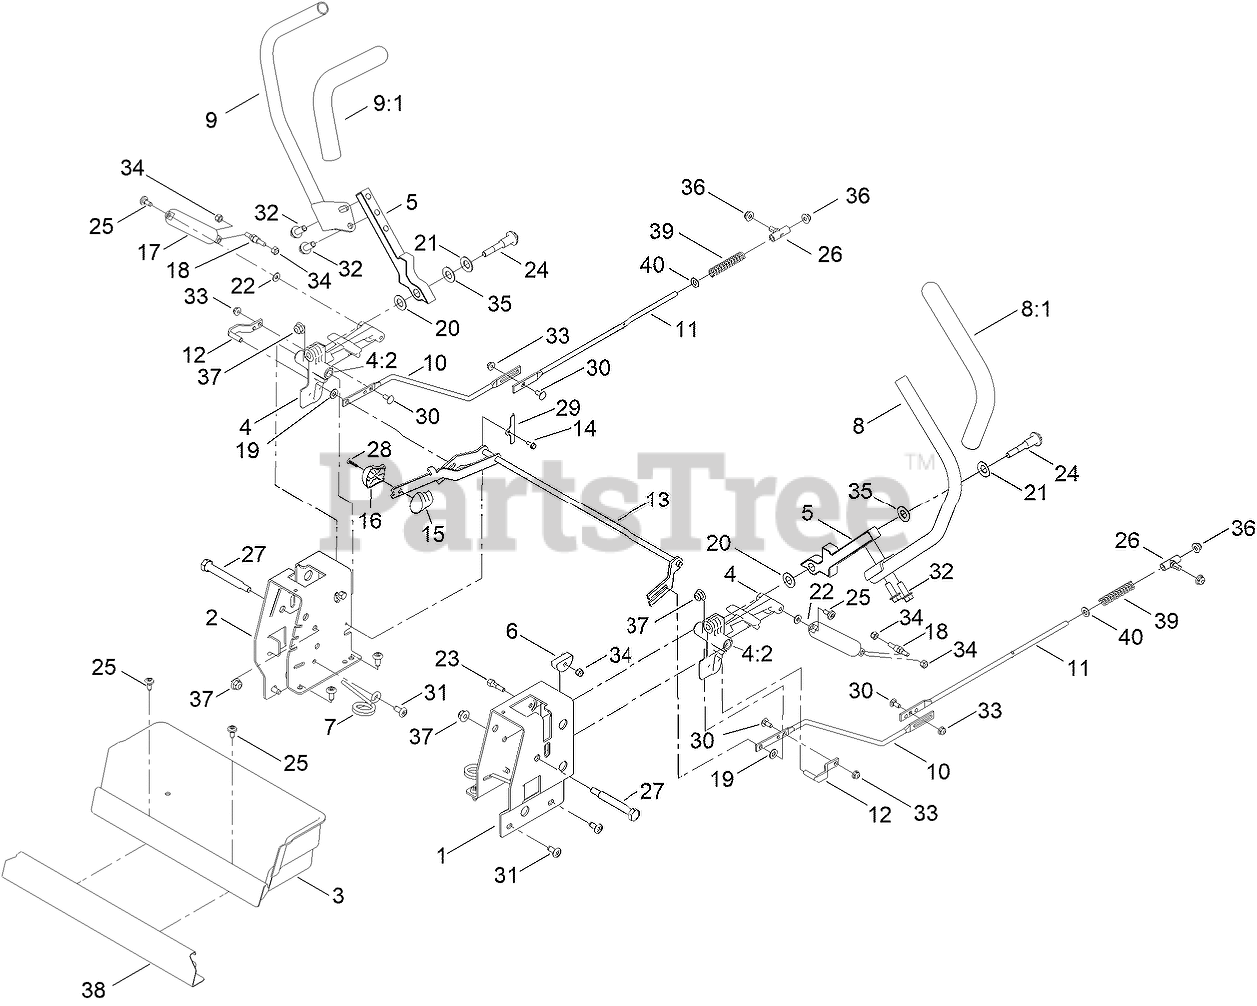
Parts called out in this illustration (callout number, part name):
1	PLATE-CONTROL BOX, LH
2	PLATE-CONTROL BOX, RH
3	BOX-STORAGE
4	ACTUATOR ARM ASM
4:2	BUSHING-FLANGE
5	ARM-CONTROL
6	ECCENTRIC
7	SPRING-TORSION
8	HANDLE-CONTROL, LH
9	HANDLE-CONTROL, RH
10	ROD-HYDRO, FRONT
11	ROD-HYDRO, REAR
12	PIN-ROD, HYDRO
13	SPEED CONTROL ASM
14	PLATE-RETAINER
15	KNOB-RH
16	KNOB-LH
17	DAMPER-NON CAVITATING
18	STUD-DAMPER
19	SPACER-NYLON
20	WASHER-NYLON
21	WASHER-BELLEVILLE
22	WASHER
23	BOLT-PIVOT, ECCENTRIC
24	BOLT-PIVOT
25	SCREW-SHOULDER
26	MOUNT-ROD, HYDRO
27	BOLT-PIVOT
28	SCREW-PPH
29	SCREW-TAPTITE
30	SCREW-CARR
32	SCREW-HHF
33	NUT-HF
34	NUT-LOCK, NI
35	WASHER
36	NUT-HF
37	NUT-HF, NI
38	PLATE-KICK
39	SPRING-COMPRESSION
40	WASHER-PLAIN
